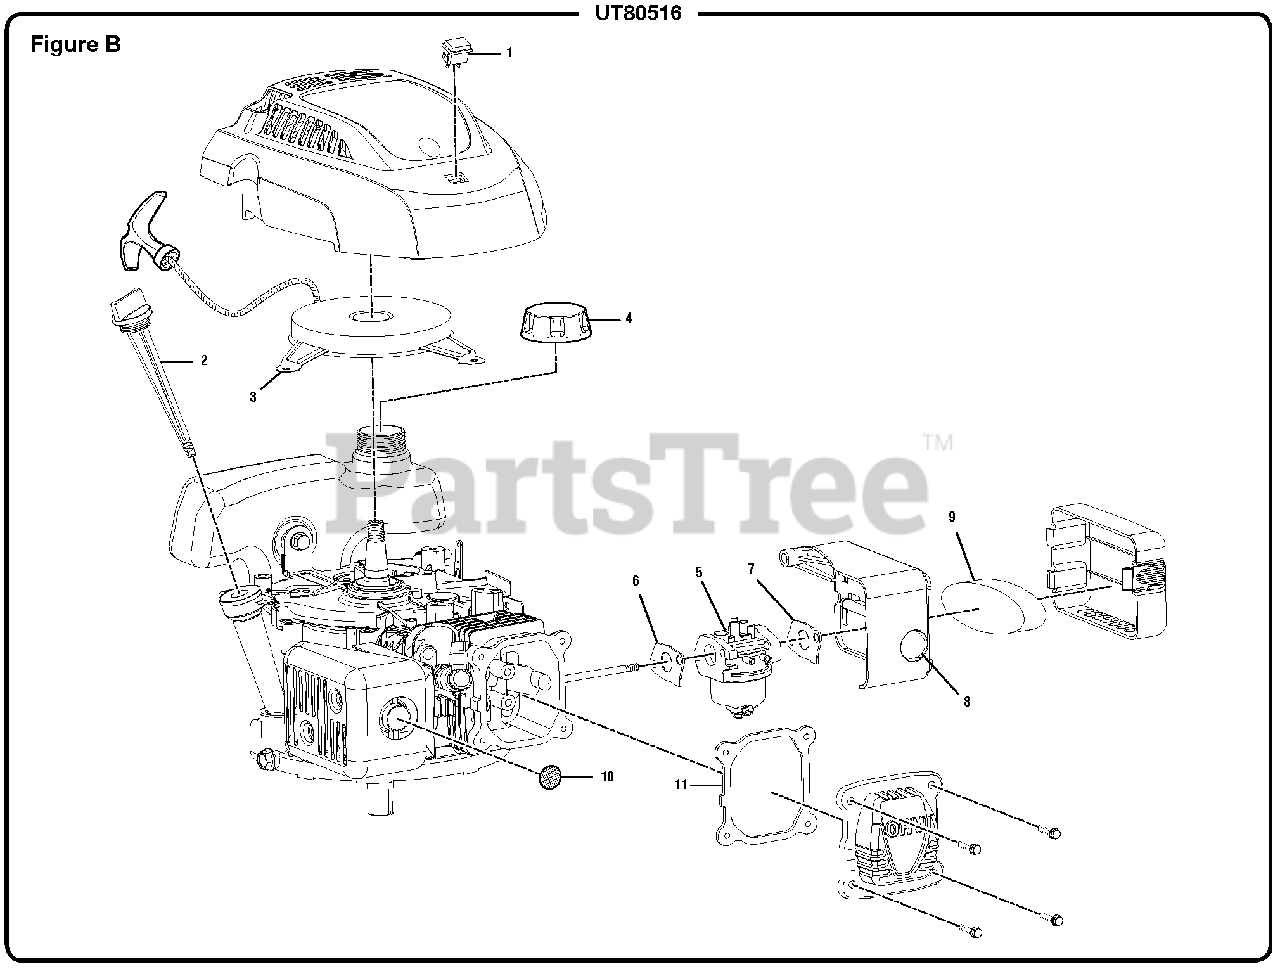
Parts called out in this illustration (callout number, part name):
1	On/Off Switch w/Cover
3	Starter Assembly
5	Carburetor
6	Inner Carburetor Gasket
7	Outer Carburetor Gasket
8	Primer Bulb
9	Air Filter
10	Spark Arrestor Screen
11	Valve Cover Gasket
